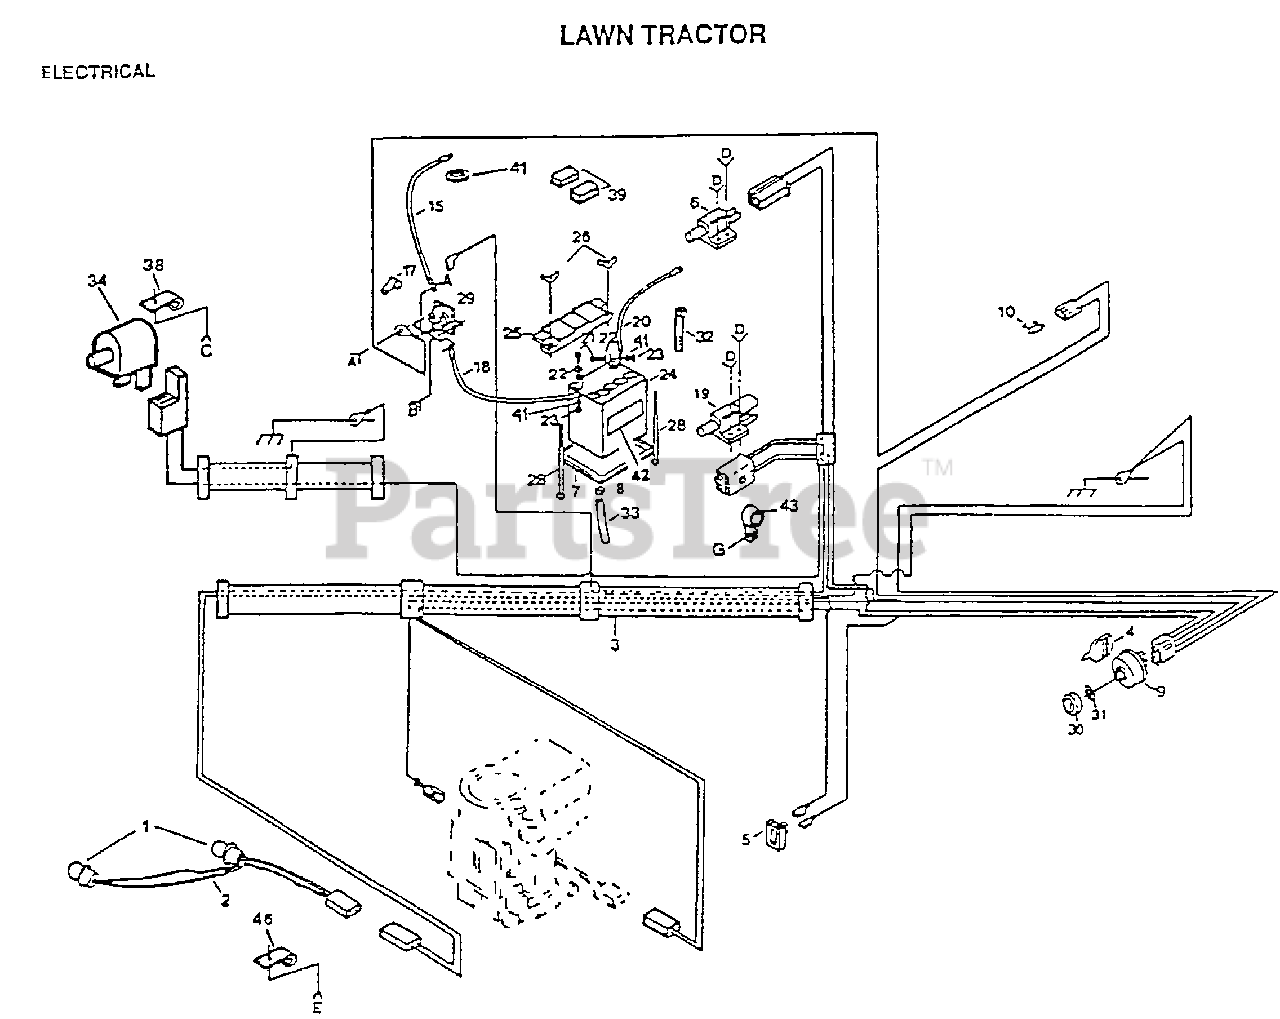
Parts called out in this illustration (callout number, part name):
2	HARNESS T
3	"HARNESS,WIRING"
5	SWITCH LT
6	SWITCH-INTER. GT
7	"TRAY T, BATTERY"
8	HOSE CLAMP T
10	FUSE HYT
18	STARTER CABLE GT
19	SWITCH INTERLOCKT
21	BOLT LT
22	WASHER
28	BOLT
32	WIRE TIE
34	SWITCH SEAT
41	LOCKWASHER
42	DECAL
43	INSUL CLIP T
46	CLIP T
